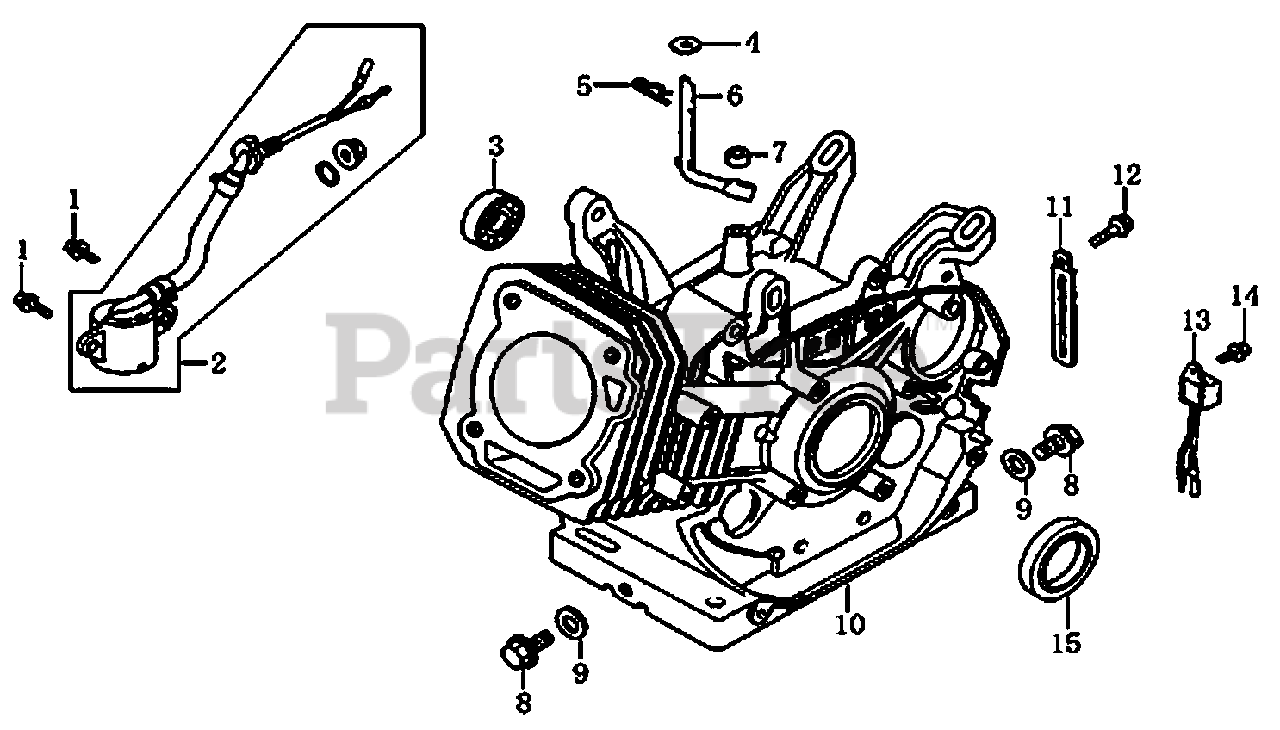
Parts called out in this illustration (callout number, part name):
1	BOLT, FLANGE, 6×14
2	SWITCH ASSY., OIL LEVEL
3	BEARING, RADIAL BALL, 6202
4	WASHER,8X16X1.2
5	PIN, LOCK, 10MM
6	SHAFT, GOVERNOR ARM
7	OIL SEAL, 8×14×4
8	BOLT, DRAIN PLUG
9	WASHER, DRAIN PLUG
10	CRANKCASE
12	BOLT, FLANGE, M6×12
13	ALERT UNIT,OIL
14	BOLT, FLANGE, M6×12
